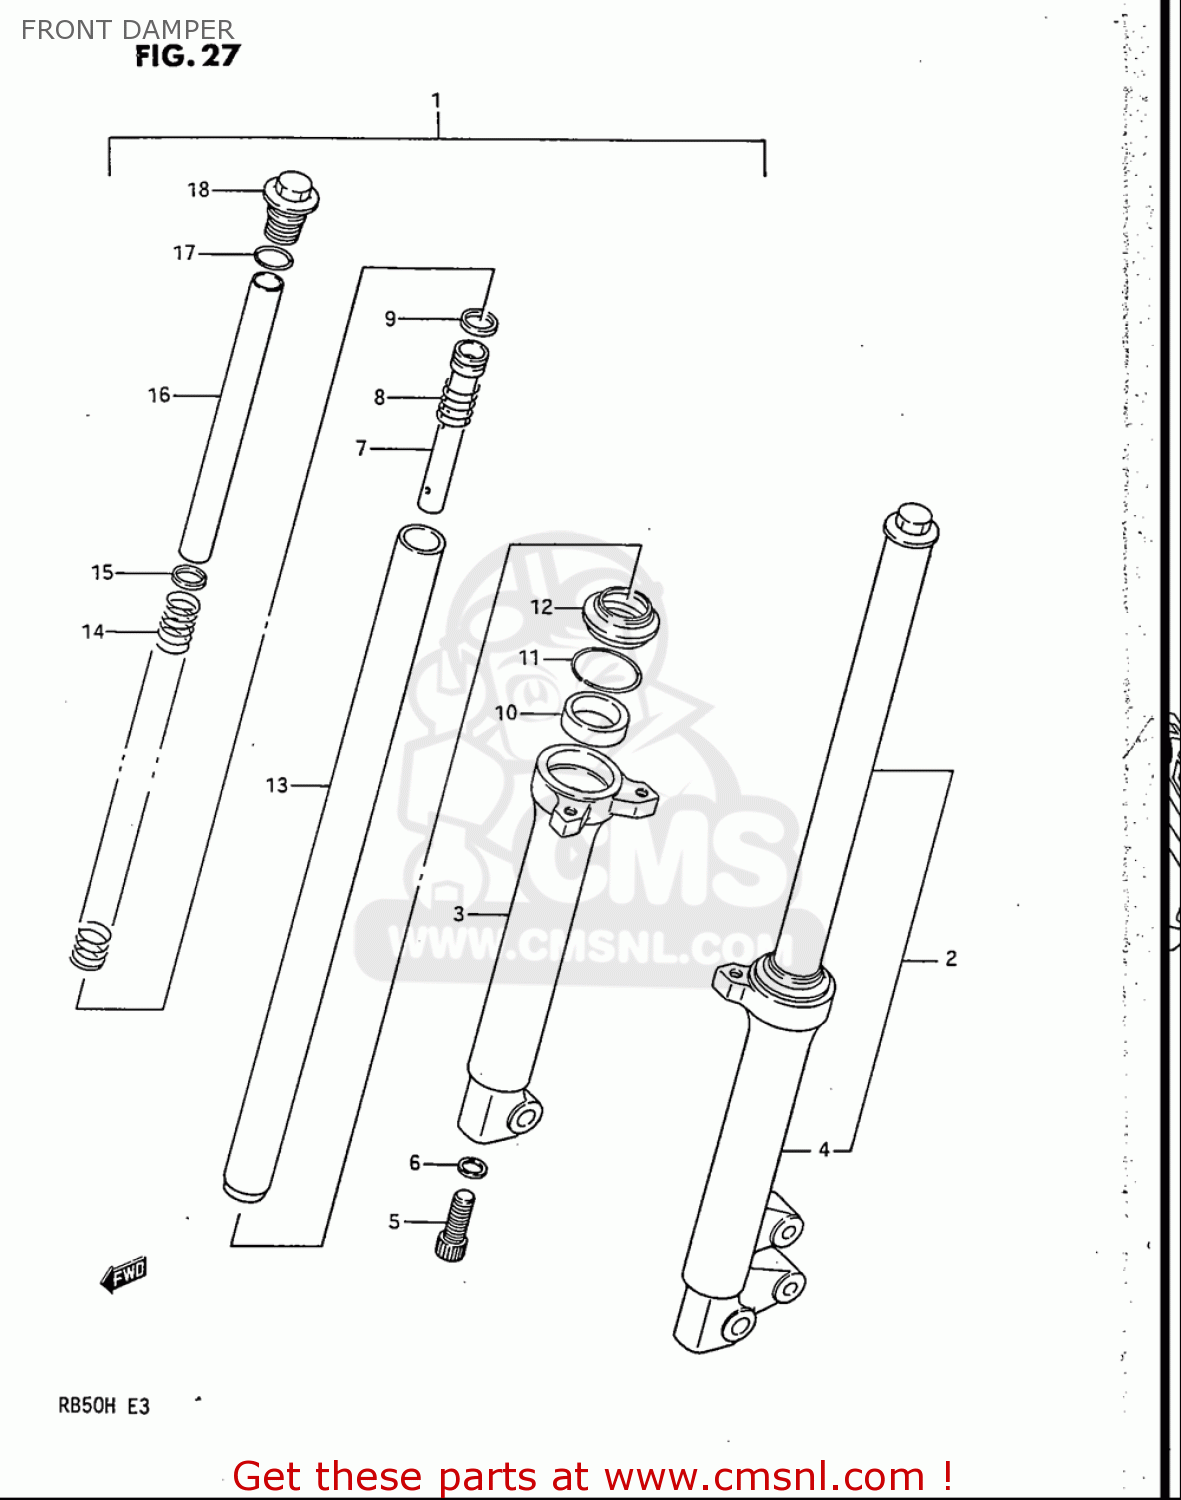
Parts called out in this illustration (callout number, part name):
5	BOLT,FORK CYLINDER(10X25)
6	GASKET (NAS)
8	SPRING,REBOUND
9	RING
10	SEAL,OIL
11	RING,OIL SEAL STOPPER
12	SEAL,DUST
13	TUBE,INNER
17	O RING(D:2.4,ID:15.8)
18	CAP
